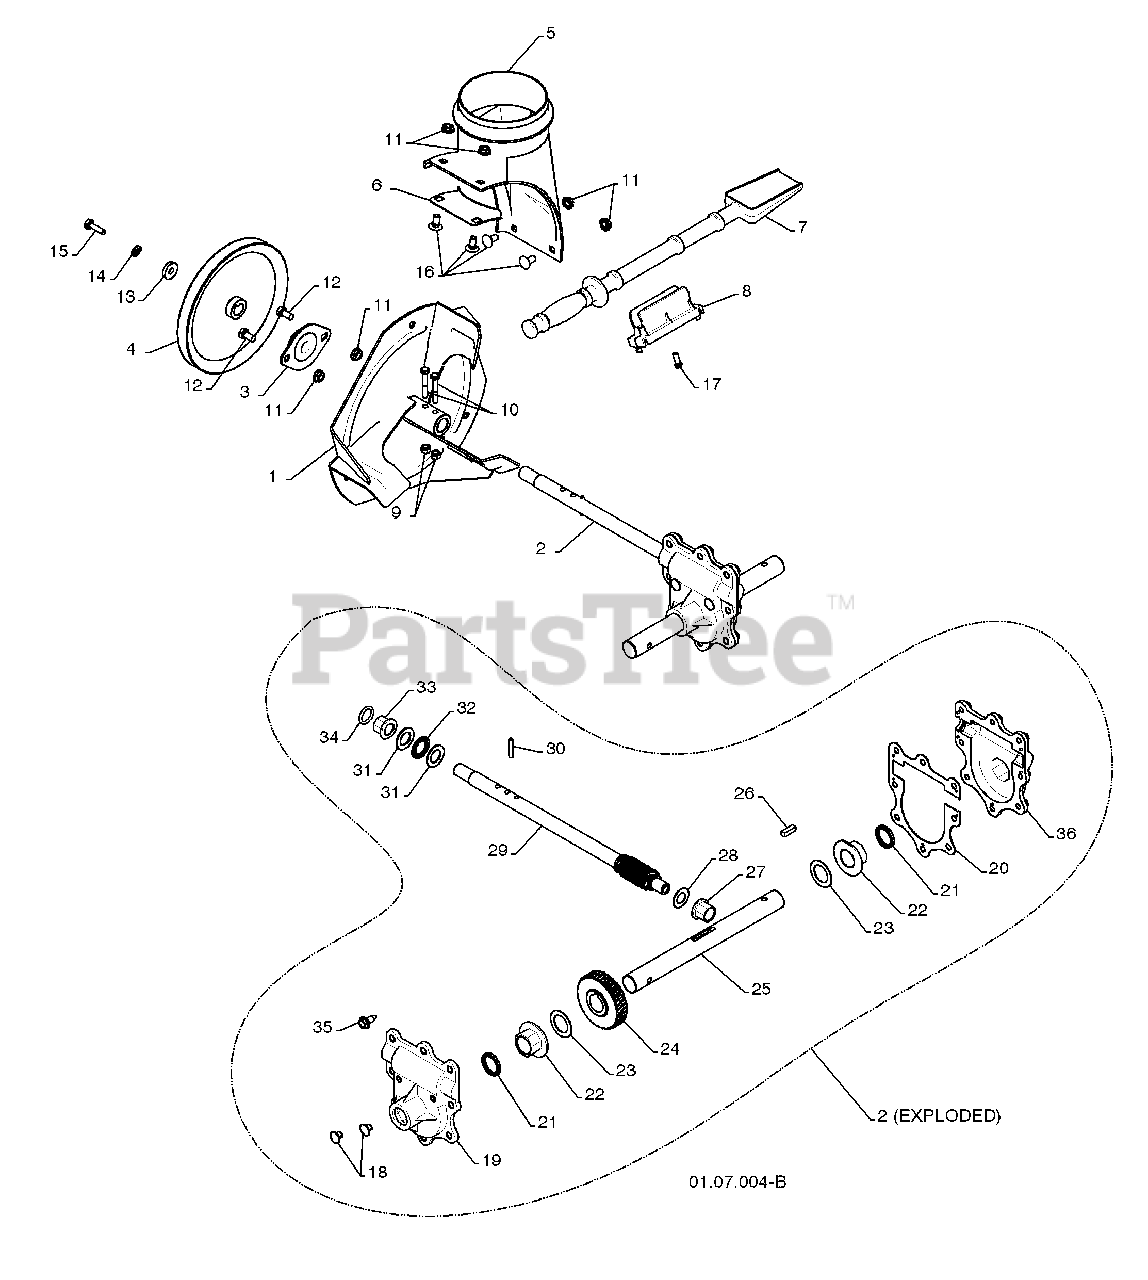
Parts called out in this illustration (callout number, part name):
1	IMPELLER
2	GEARBOX ASSEMBLY
4	IMPELLER PULLEY
5	DISCHARGE BASE
6	CORNER BRACKET
7	CLEAN OUT TOOL
9	NUT 1/4-20
10	SCREW 1/4-20 X .625
11	NUT 5/16-18
12	SCREW 5/16-18 X .625
14	LOCKWASHER 5/16
15	SCREW 5/16-18 X 1.00
16	CARRIAGE BOLT
17	SCREW 13-16 X .625
18	PLUG
19	GEARBOX COVER RH
20	GASKET
21	SEAL
22	BEARING
23	THRUST WASHER 1.00
24	WORM GEAR
25	AUGER SHAFT
26	SQUARE KEY
27	BEARING
28	THRUST WASHER
29	IMPELLER SHAFT
30	ROLL PIN
31	THRUST WASHER
32	THRUST BEARING
35	SCREW 5/16-18 X .750
36	GEARBOX COVER LH
